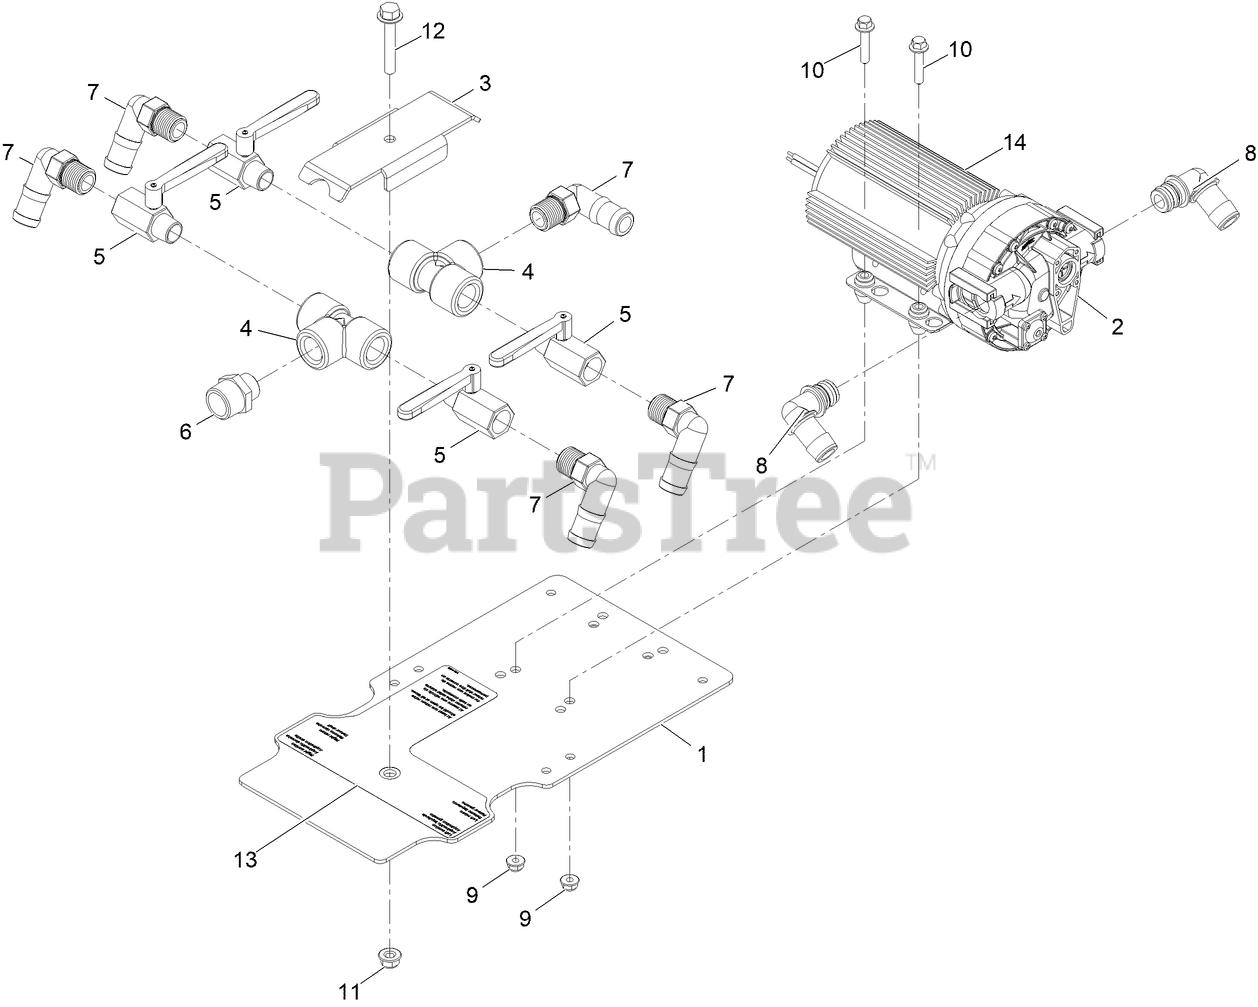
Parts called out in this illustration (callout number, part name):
1	MOUNT-PLATE, LIQUID VALVE
2	PUMP-5.3 GPM
3	PLATE-CLAMP, LIQUID VALVE
5	VALVE-CHROME, 1/2
6	FITTING-NIPPLE
7	ELBOW-90
8	FITTING-ELBOW
9	Nut-Hex Flange
10	SCREW-HHF
11	Nut-Hex Flange
12	SCREW-HHF
13	DECAL-VALVE, TANK
14	HEATSINK-3.0""
